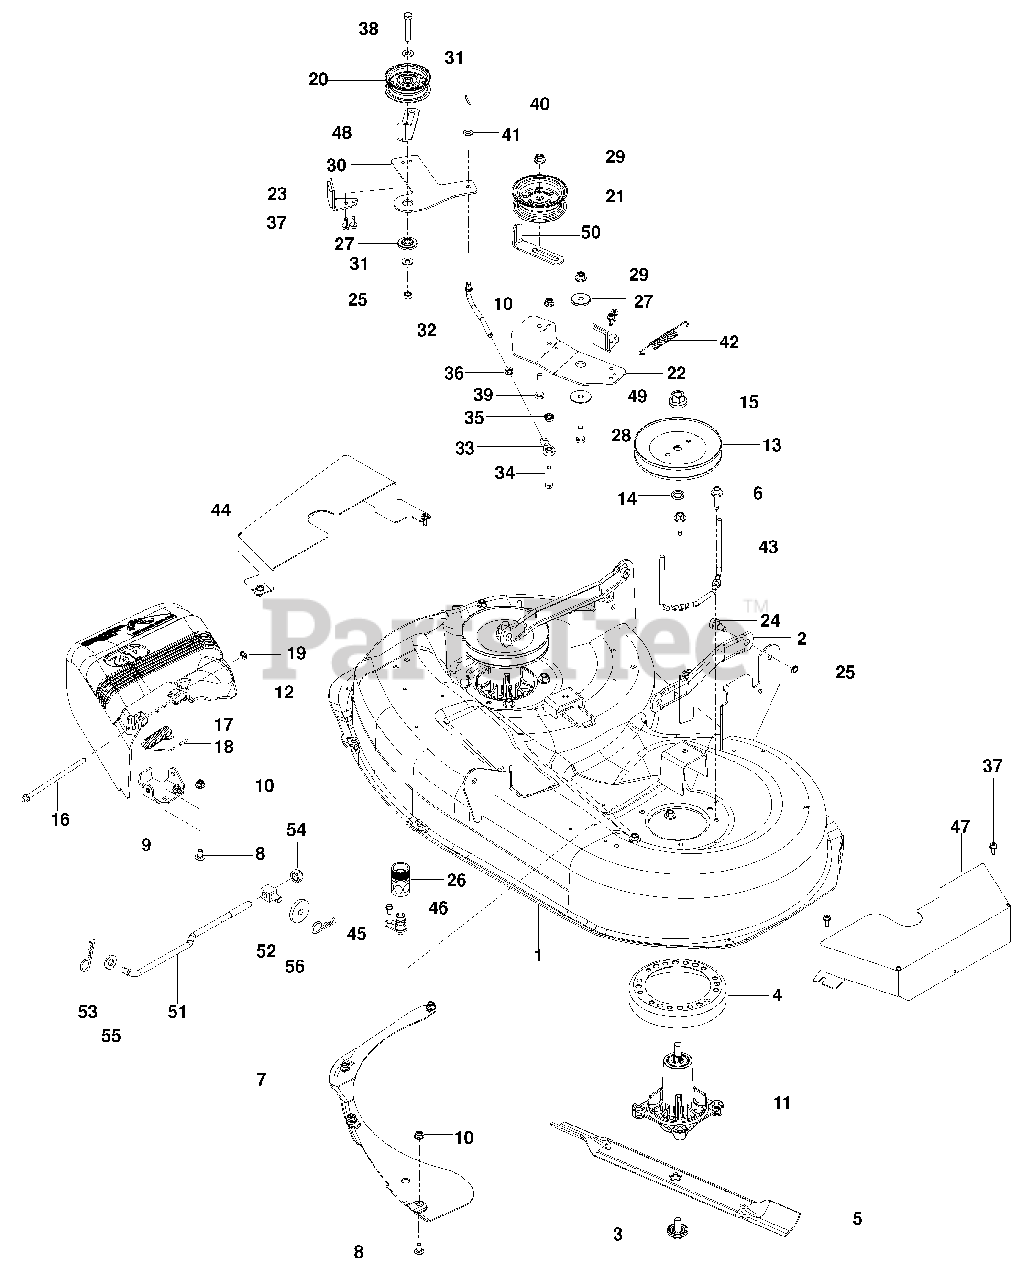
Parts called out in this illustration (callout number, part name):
1	DECKw/SAFETYDECALS
2	SUSPENSIONARM,REAR
3	BOLT,WASHER
4	STRIPPER,ROUND
5	BLADE42"
6	SCREW,WASHERHEAD
7	BAFFLE,DECK
8	RHSNB5/16-18x5/8
9	BRACKET,DEFLECTOR
10	NUT5/16-18HEXFLGNYL
11	MANDREL
12	SHIELD,DEFLECTOR
13	PULLEY,MANDREL
14	WASHER-SPACER
15	NUT9/16TOPCNTRLK
16	ROD,HINGE
17	SPRING,TORSION
18	CAP,SLEEVE
19	PUSHNUT
20	PULLEY,IDLER
21	PULLEY,IDLER
23	ARM,LHBRAKE
24	BOLT3/8-16x3/8SKTHD
25	NUT3/8-16HEXJAMNYLOC
26	QUICKCONNECT
27	SPACERRETAINER
28	HCS3/8-16x1
29	NUT3/8-16HEXFLGNYLOC
31	WASHER3/8SAEFLT
32	LINKAGE,DECKBRAKE
33	BALLEND,RH
34	HCS5/16-18x1 1/2
35	NUT5/16-18HEXWHIZLK
36	NUT,5/16-18HEX
37	SCREW 1/4-20x5/8
38	HCS3/8-16x2
39	HCS3/8-16x1 3/4
40	HAIRPIN
41	WASHER5/16SAEFLAT
42	SPRING,RETURN
43	KEEPER,PULLEY
44	BELTSHIELD,RT
45	WASHOUTPORT
46	BOLT 1/4-20x 1/2
47	BELTSHIELD,LT
48	GUIDE,BELT
49	WASHER,FRICTION
50	GUIDE,BELT
51	LINK,SUSPENSION
54	NUT7/16-20HEXNYLOC
55	WASHER,SAE
56	HEAVYWASHER
